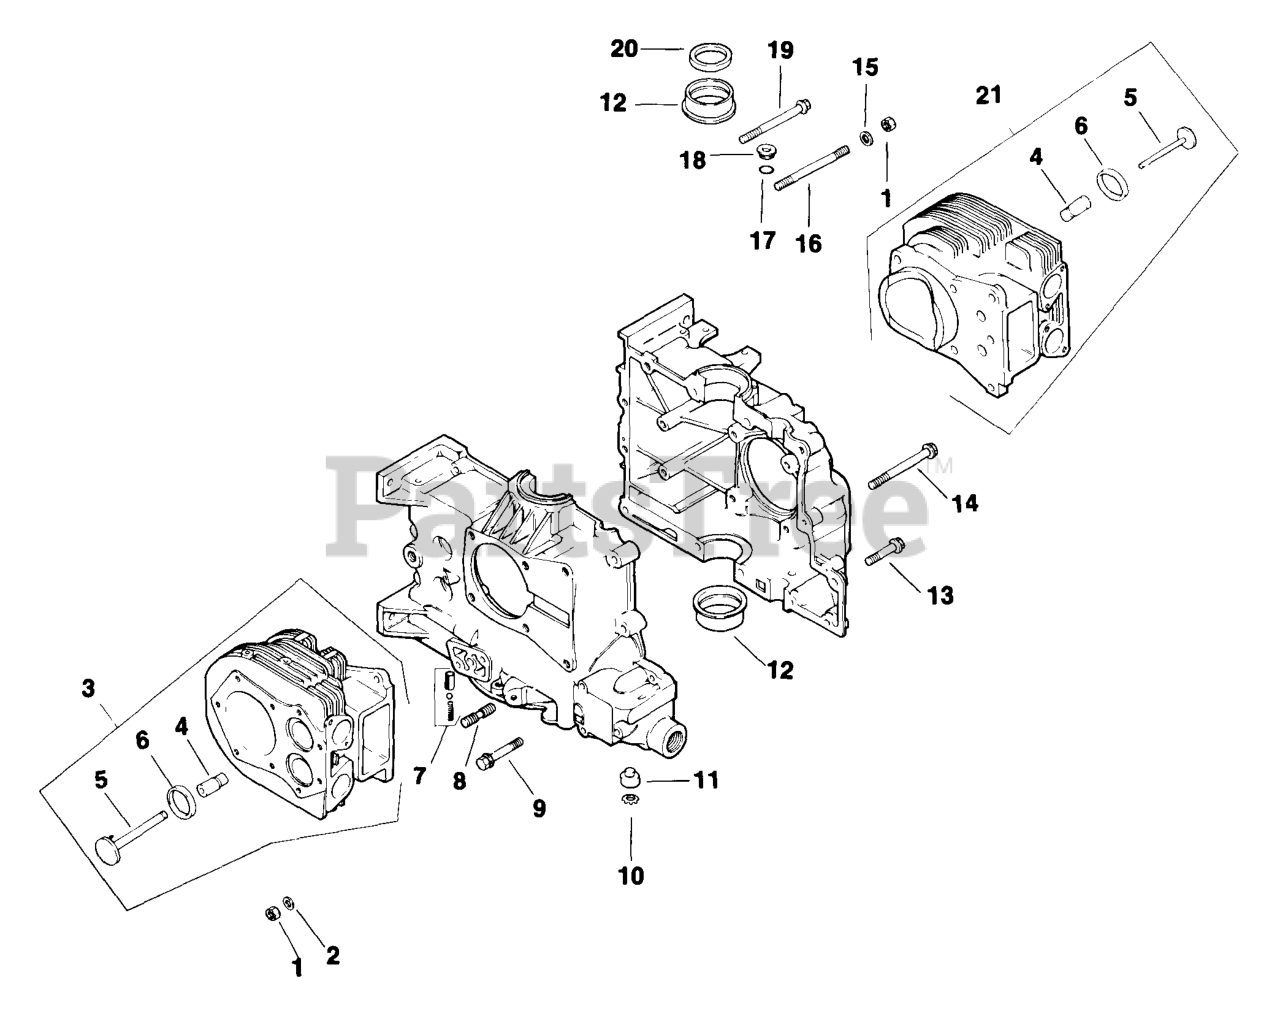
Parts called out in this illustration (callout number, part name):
1	NUT, 5/16-18 GRADE 5 USE 25 100 22-S
2	WASHER, FLAT 5/16"
3	KIT, CYLINDER BARREL - (#DSC)
4	GUIDE - USE 52 316 08
5	VALVE, EXHAUST
6	INSERT - (#DSC)
7	KIT, OIL RELIEF - DISCONTINUED
8	STUD - DISCONTINUED
11	SHAFT - DISCONTINUED
12	BEARING .010
12	BEARING .020
13	SCREW - DISCONTINUED
14	SCREW - DISCONTINUED
16	SCREW - USE 25 086 11
17	O-RING - DISCONTINUED
21	KIT, CYLINDER BARREL
